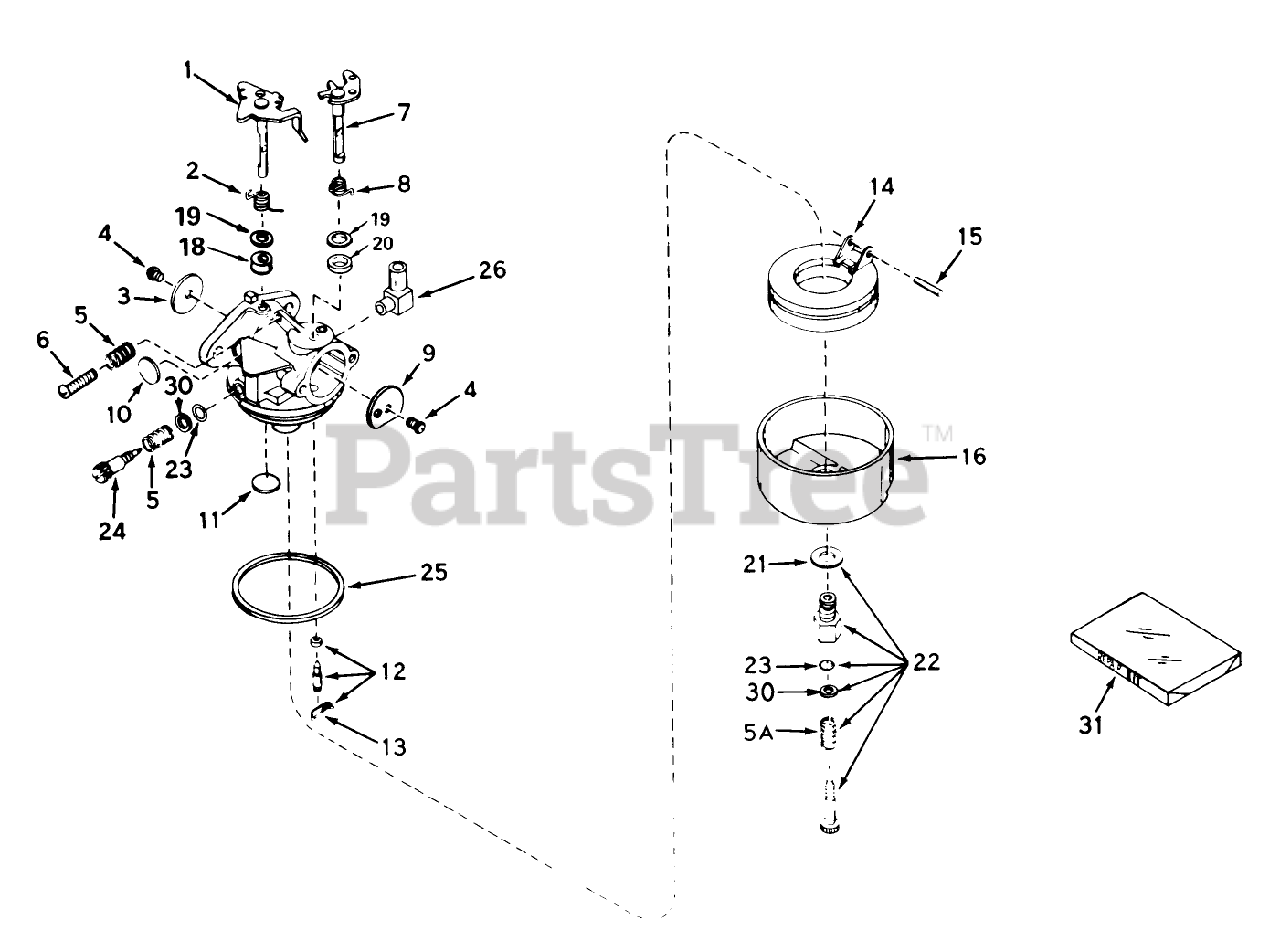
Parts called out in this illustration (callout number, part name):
1	Shaft/Lever-Throttle
2	Spring-Return, Throttle
3	Shutter-Throttle
4	Screw-Shutter
5	Spring-Tension
5A	Spring
6	Screw-Throttle Crack Screw / Idle Speed
7	Shaft Lever Assy., Choke
8	Spring-Choke
9	Shutter-Choke
10	Plug-Welch, Idle Mixture Well
11	Plug-Welch, Atmospheric Vent
12	Inlet Needle, Seat Clip Assy. (Incl. No. 13)
13	Clip-Spring
14	Float
15	Shaft-Float
16	Bowl-Float (no drain)
18	Seal-Dust
19	Washer-Seal, Dust
20	Seal-Dust
21	Washer-Bowl Nut
22	Adjustment Screw Assy., Main (Incl. Nos. 5A, 21 23)
23	ORing
24	Screw, Idle Adj.
25	O Ring-Bowl, Float
26	Fitting-Fuel Inlet
30	Washer
31	Repair Kit
